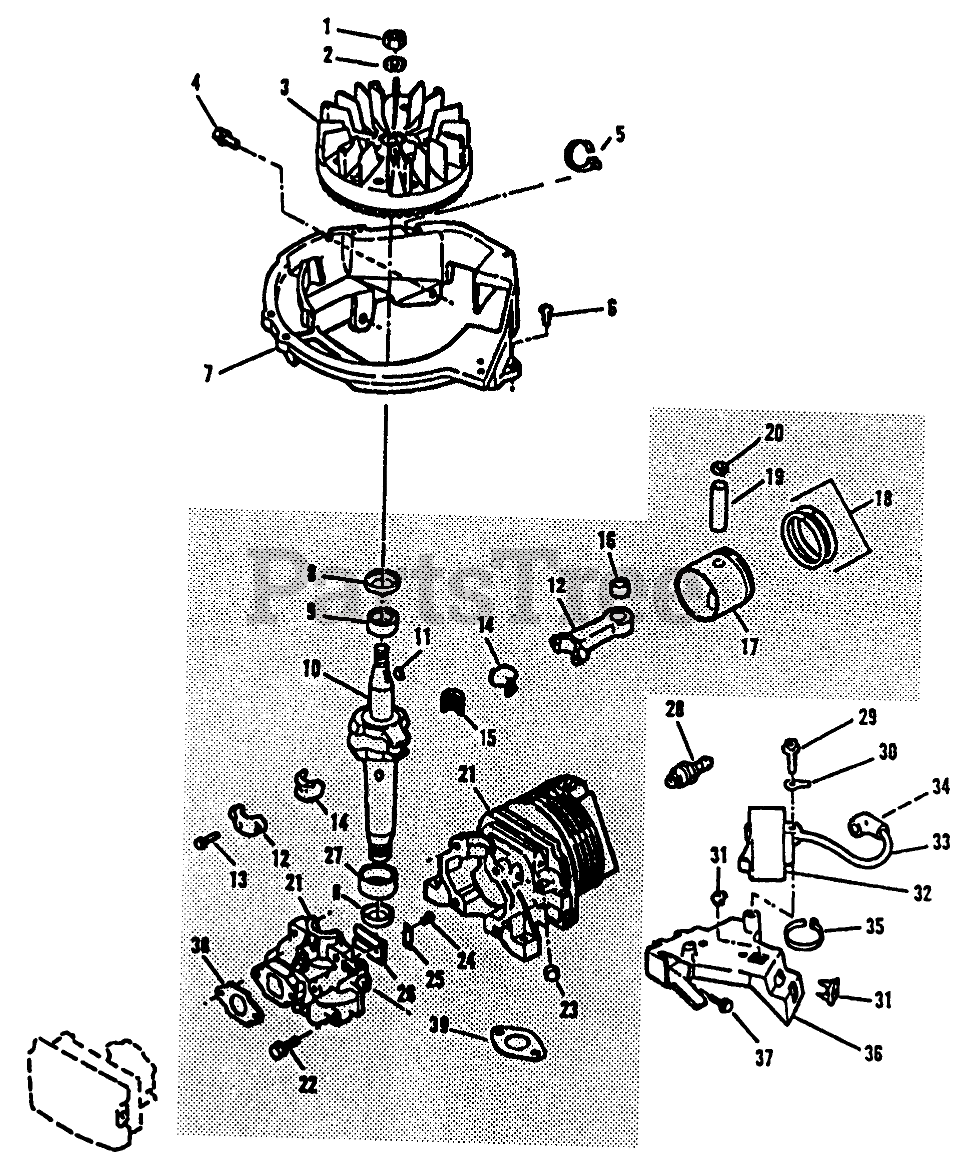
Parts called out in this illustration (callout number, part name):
1	NUT
2	WASHER-LOCK
3	FLYWHEEL AY. F
4	SCREW F
5	STRAP-TIE
6	SCREW F
7	BASE SHROUD F
8	SEAL-OIL
9	BEARING V
10	Crankshaft
11	KEY
13	SCREW-HSH
14	LINER ASM
15	BEARING-NEEDLE
16	BEARING AY F
18	F-RING SET
19	PIN-WRIST VF
20	RING-RETAINING
21	Cylinder and Crk-c Cover Asy
22	SCREW-H.W.HD. F
23	PLUG-CORE VF
24	SCREW-HH
25	PLATE-BACKUP, REED
26	REED-CARBURETOR
27	BEARING V
28	Spark Plug
29	SCREW F
30	TERMINAL S
31	NUT-CLIP
32	Module-C.D. Ignition & Lead
33	HT LEAD&COVER XEV
35	TIE-CABLE
36	C.D. BRKT F
37	SCREW F
38	GASKET CARB S
39	Gasket
